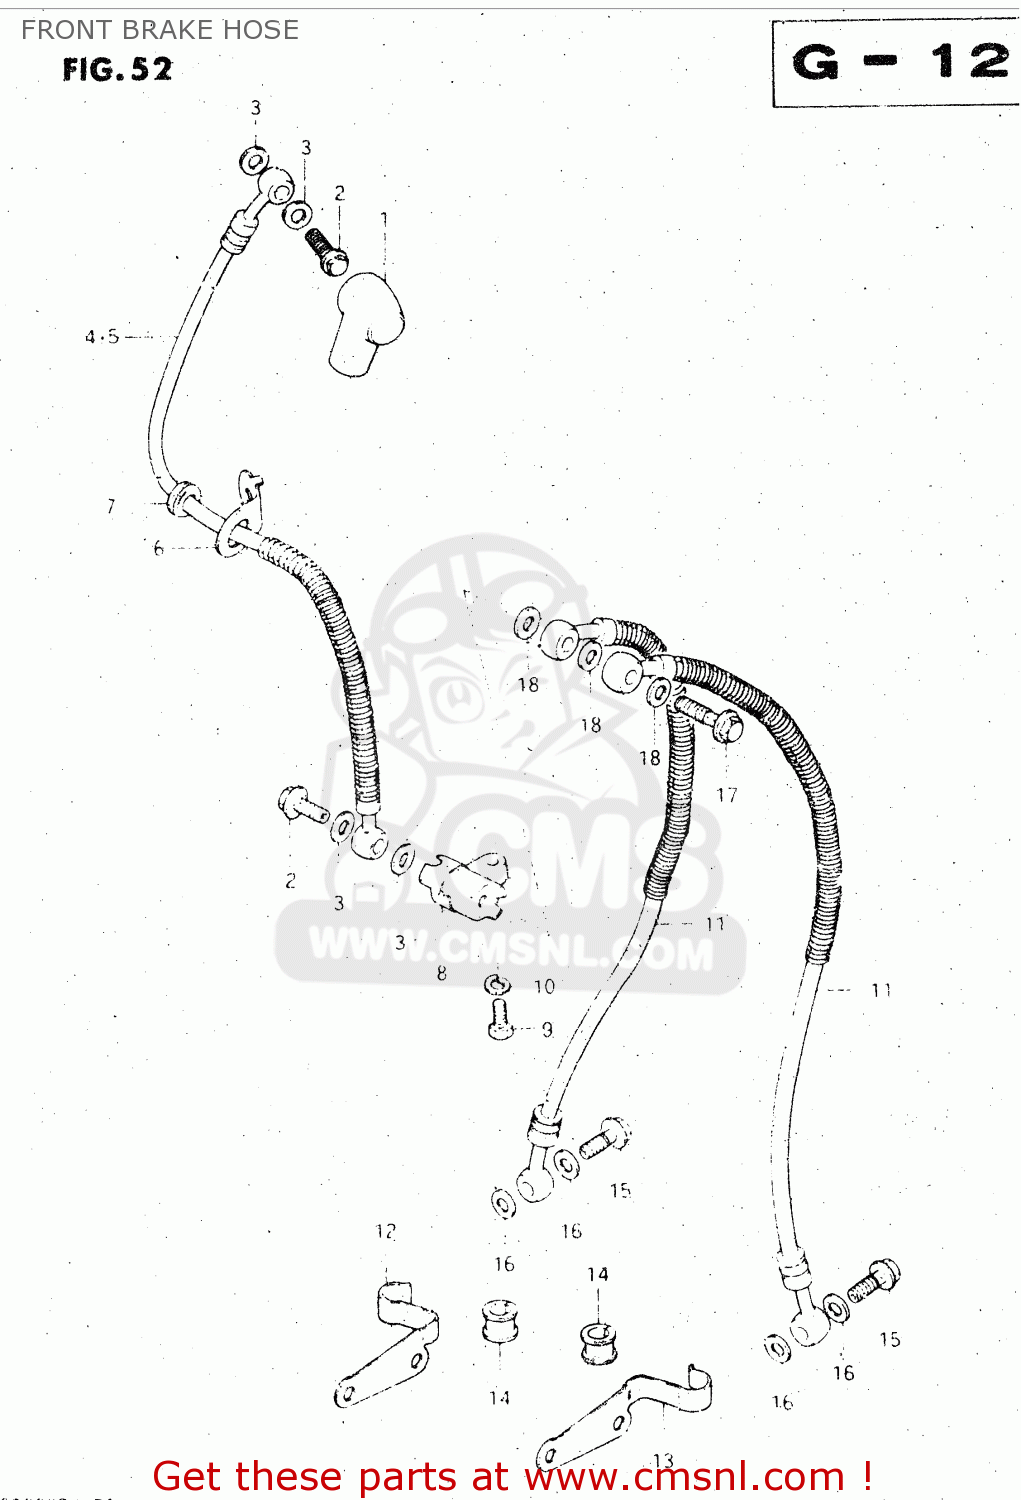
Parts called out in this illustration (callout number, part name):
1	BOOT,MASTER CYLINDER
2	BOLT,UNION
3	WASHER
4	HOSE,FRONT BRAKE
5	HOSE,FRONT BRAKE
6	GUIDE,BRAKE HOSE
7	GROMMET
8	JOINT,BRAKE HOSE
9	BOLT
10	LOCK WASHER
11	HOSE,BRAKE NO.2
12	CLAMP,FRONT BRAKE HOSE
13	CLAMP,FRONT BRAKE HOSE
14	BUSH,BRAKE HOSE GUIDE,NO.2
15	BOLT,UNION
16	WASHER
17	BOLT,UNION
18	WASHER
